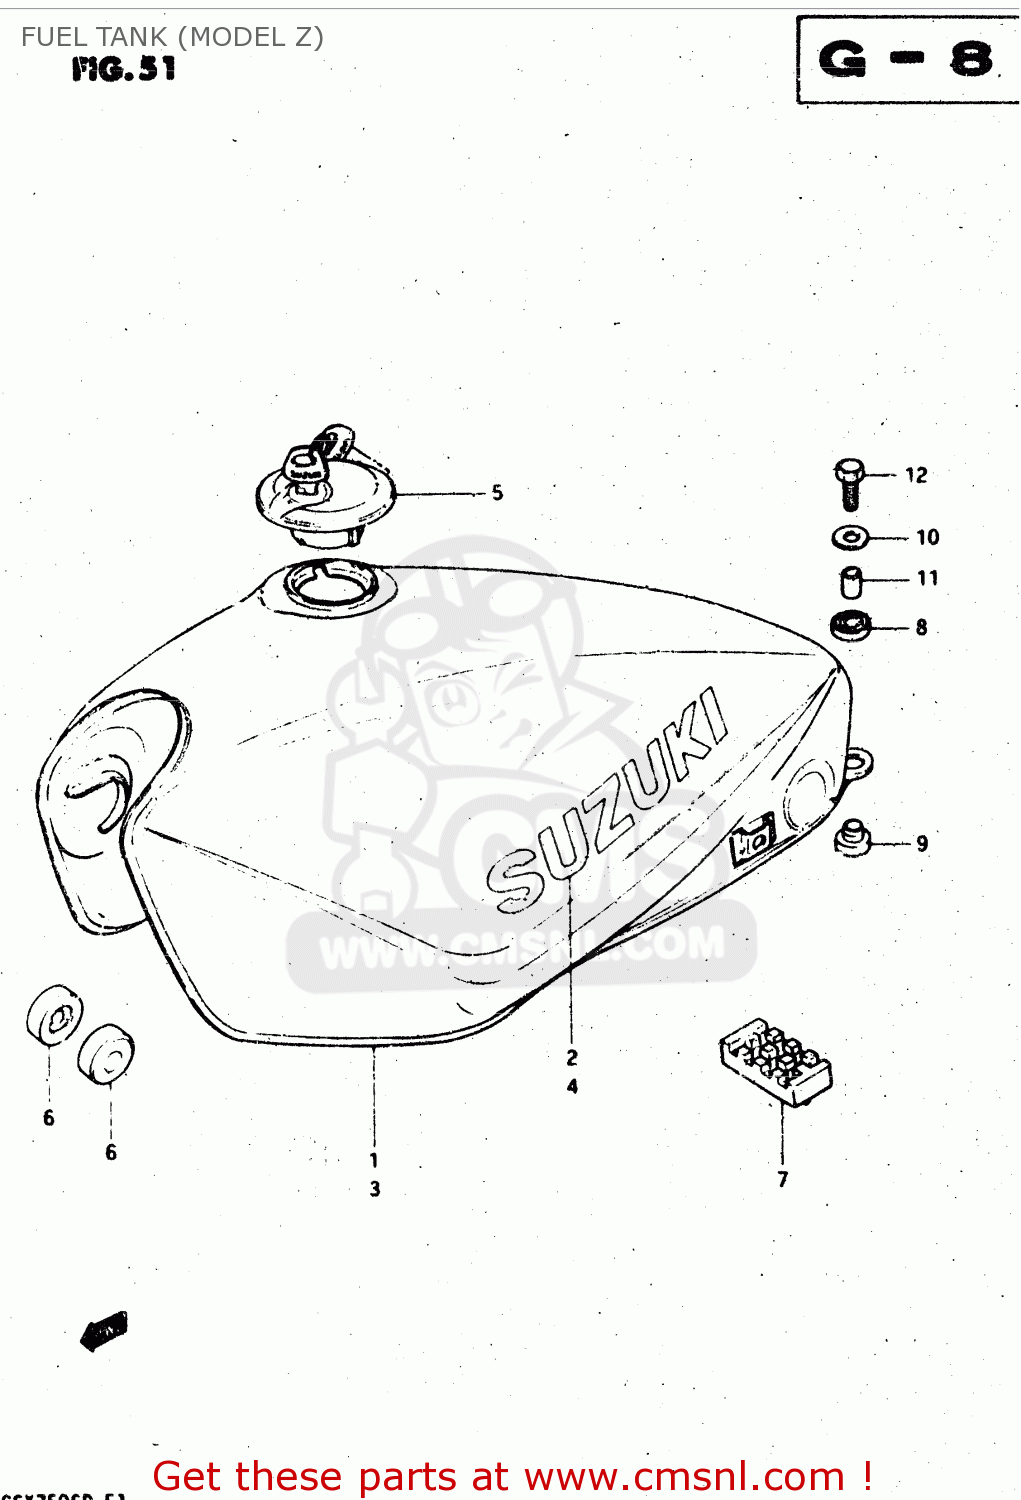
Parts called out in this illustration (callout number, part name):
1	TANK, FUEL (SILVER)
2	EMBLEM(ORANGE)
3	TANK, FUEL (RED)
4	EMBLEM(WHITE)
5	CAP SET,FUEL TANK
6	CUSHION
7	CUSHION,FUEL TANK CTR
8	CUSHION
9	CUSHION
10	WASHER (6.5X24X1.6)
11	SPACER
12	BOLT
